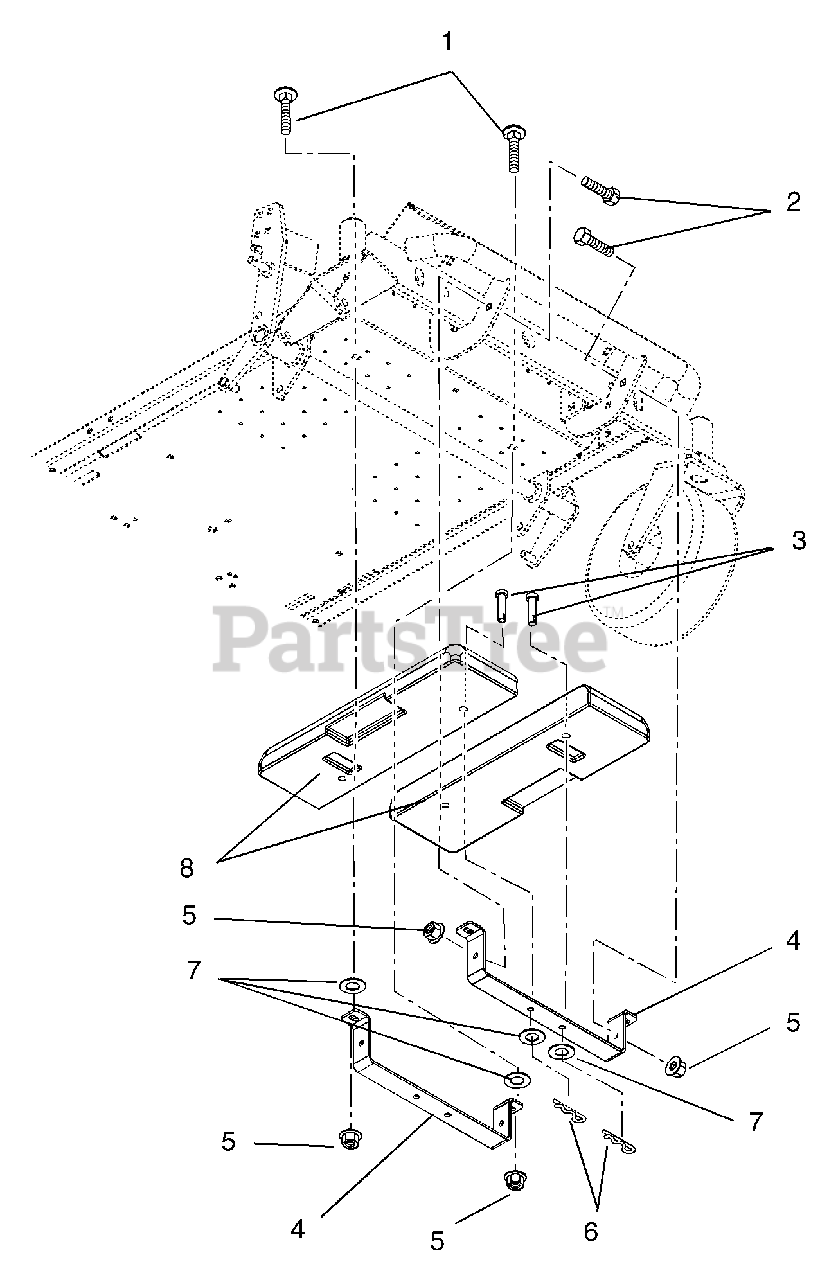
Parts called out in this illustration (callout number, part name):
1	Bolt-Round Head Square Neck .38-16 x 1.00 Grade 5
2	Bolt-Hex .38-16 x 1.00 Grade 5
3	Pin-Clevis .494 x 2.50
4	Bracket, Weight
5	Nut-Locking-Top-Flange .38-16
6	Pin-Hair-External .12 x .31 x 2.37
7	Washer-Flat-Steel .515 x 1.625 x .250
8	Counterweight
